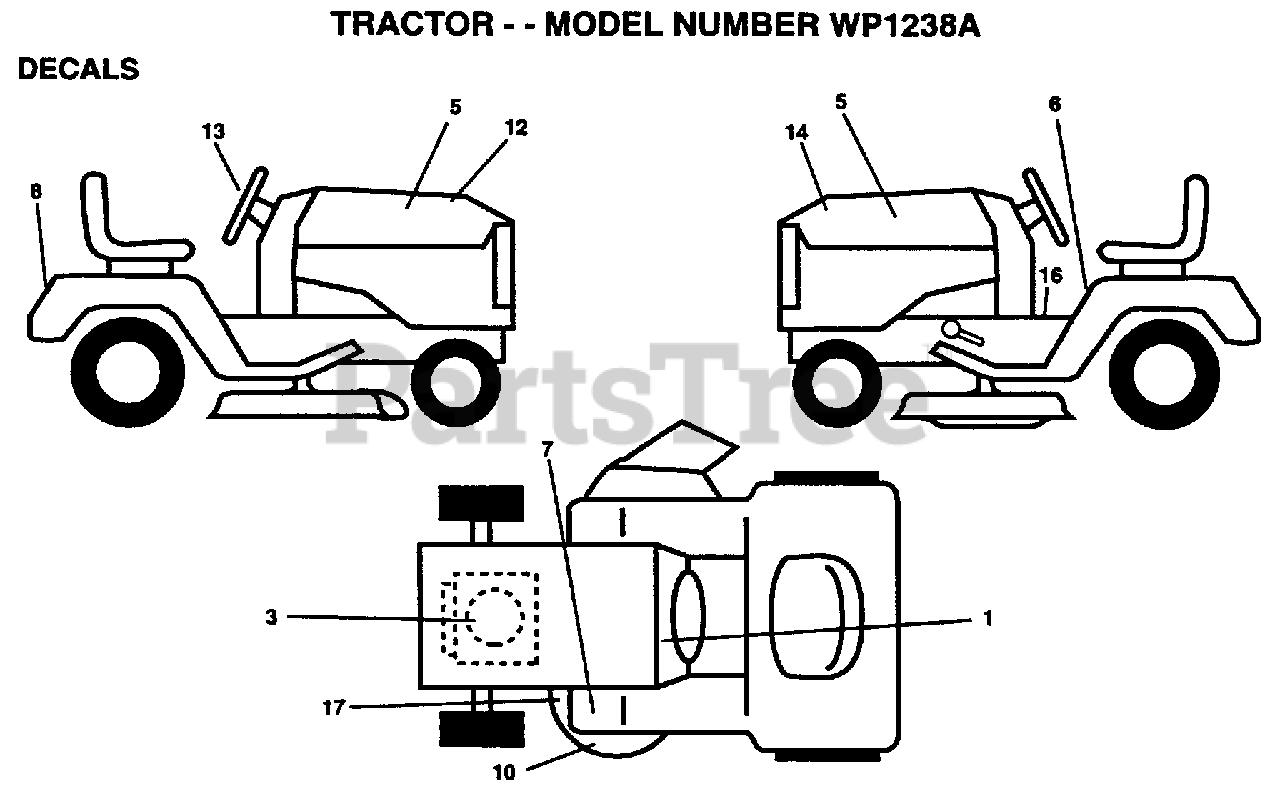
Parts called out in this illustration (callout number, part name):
1	DECAL.DASH.INST.
3	DECAL.ENG.271967
5	DECAL.HOOD.LOGO.
6	DECAL
8	DECAL, MODEL HOOD
12	DECAL.HD.RH.WINST
13	DECAL, WHEEL CAP
14	DECAL.HD.LH.WINST
16	DECAL BRAK PARK
17	DECAL
